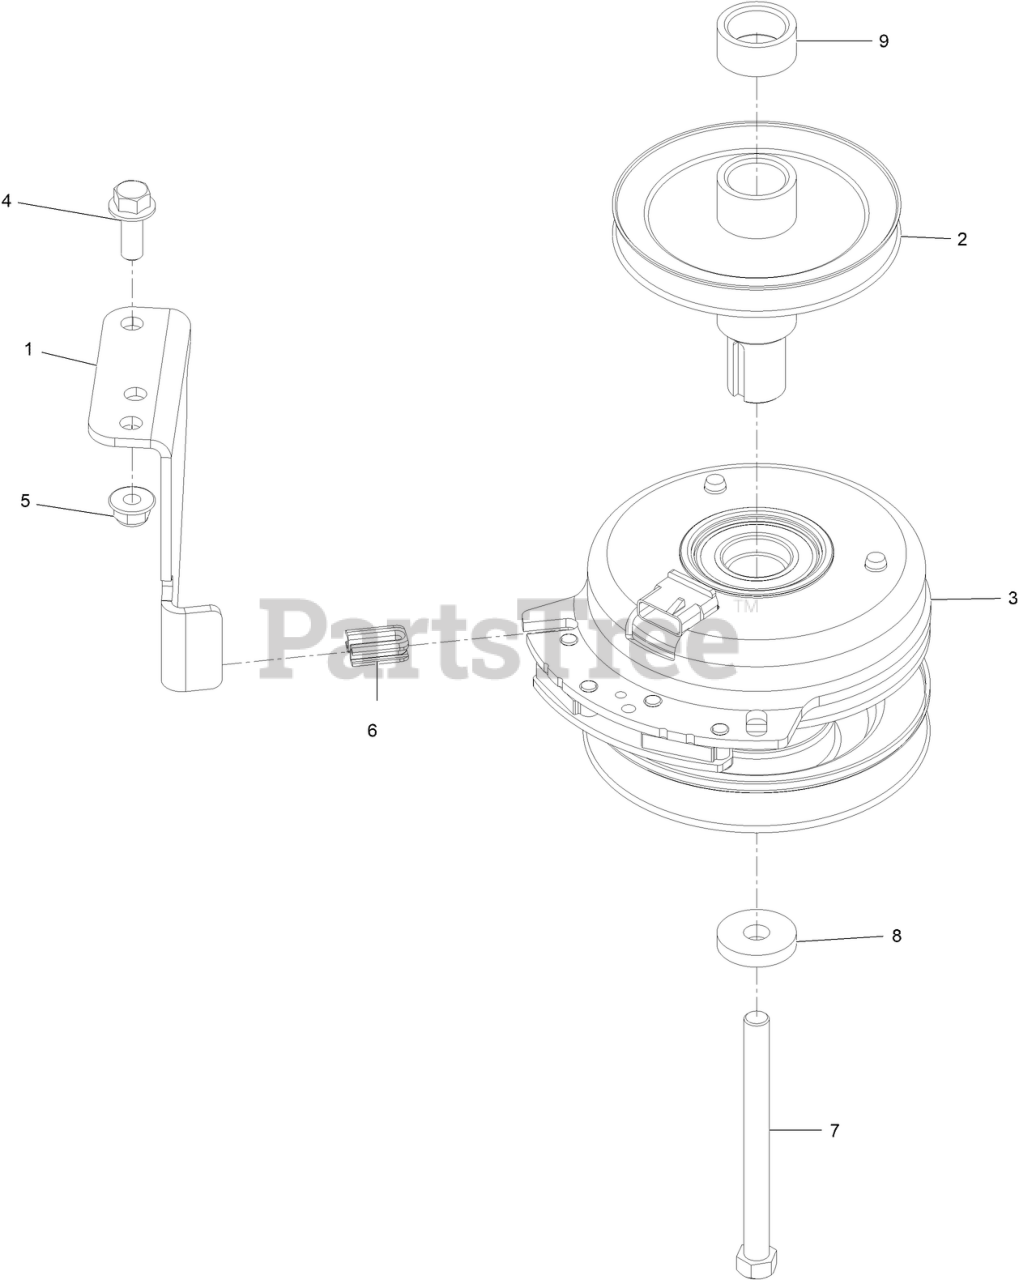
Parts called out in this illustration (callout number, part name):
1	STOP-CLUTCH (WIDE)
2	Pulley-Engine
3	Valve & Seat Kit
4	SCREW-HHF 3/8-16 X 1
5	NUT-HF, NI
6	ISOLATOR-CLUTCH
7	SCREW-HH
8	WASHER
9	Spacer-Engine Pulley
